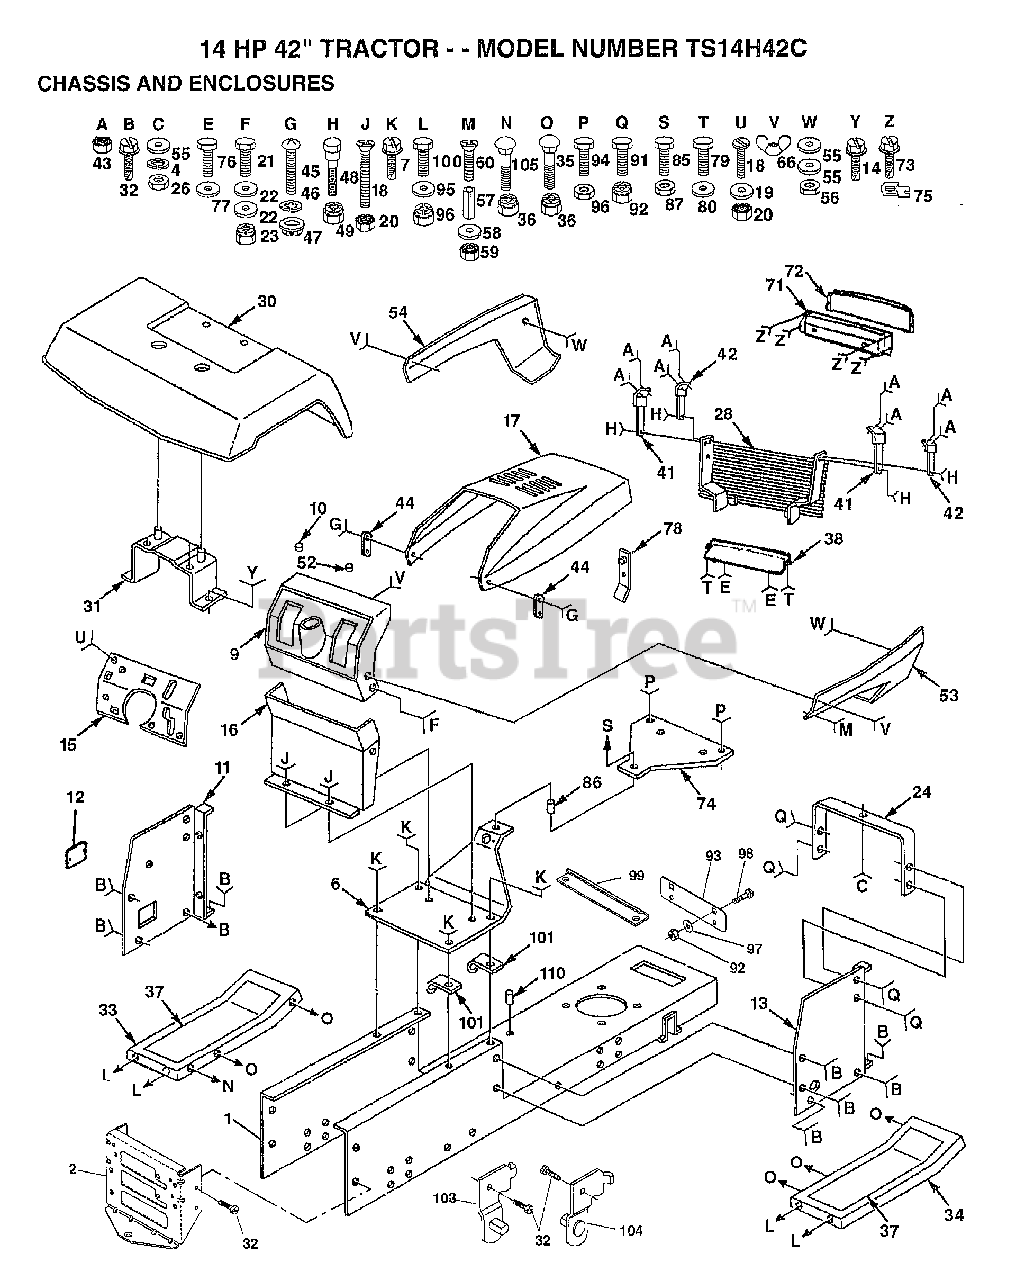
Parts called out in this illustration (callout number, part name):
4	LOCKWASHER
7	SCREW
9	DASHBOARD BLACK
10	PLUG BUTTON T
11	PANEL.DASH.LH
12	COVER ACCESS
13	PANEL.DASH.RH
14	SCREW
15	PLATE.SILKSCRND
16	DASH ASSY LT
18	SCREW
19	WASHER
21	BOLT
22	WASHER
23	NUT
24	SUPPORT ASS'Y
31	BRACKET SUPT FEND
32	SCREW
35	BOLT
36	NUT
37	FOOTREST PAD
43	NUT
44	HOOD LATCH T
45	SCREW
46	LOCKWASHER
47	WELDNUT
49	NUT
52	PLUG-DASH T
54	"PANEL,SIDE LH"
55	WASHER PM
57	SPACER LT
58	WASHER
60	SCREW
72	LENS LT
74	PLATE.SUPT.BATTER
75	"""J"" FASTENER LT"
76	SCREW
77	WASHER
79	SCREW HEX CRT
80	WASHER
85	BOLT
86	SPACER
87	NUT
91	BOLT
92	NUT
93	PLATE EXTEN FEND
94	BOLT
95	WASHER
96	NUT
97	WASHER
99	SPACER FENDER LT
100	BOLT
101	"CLIP,INSULATOR"
103	BRACKET ASM LH
104	BRACKET ASM RH
